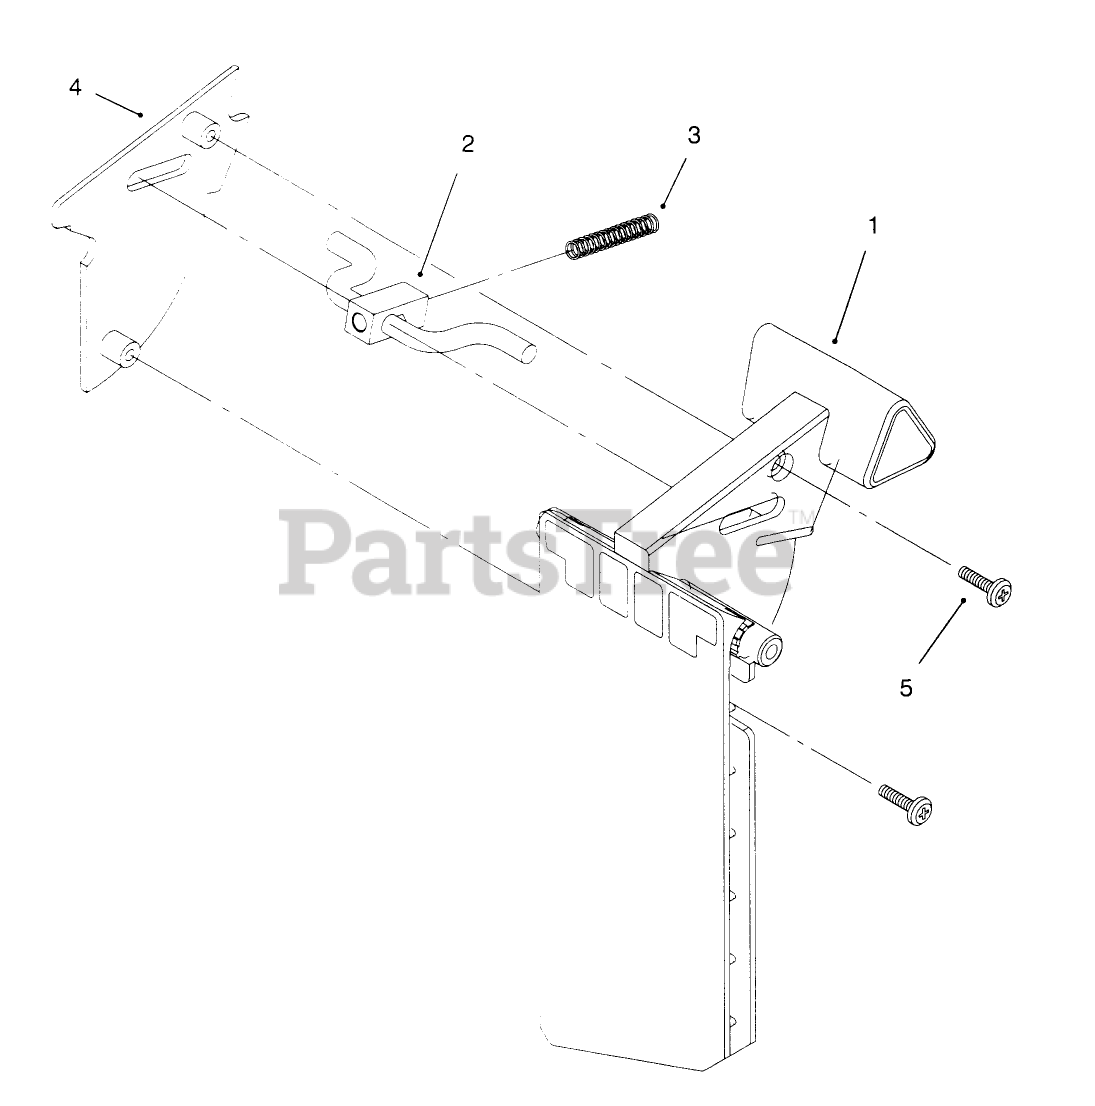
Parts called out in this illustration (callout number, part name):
1	DOOR-DISCHARGE
2	LATCH-DOOR
3	SPRING-COMPRESSION, LATCH
4	DOOR COVER
